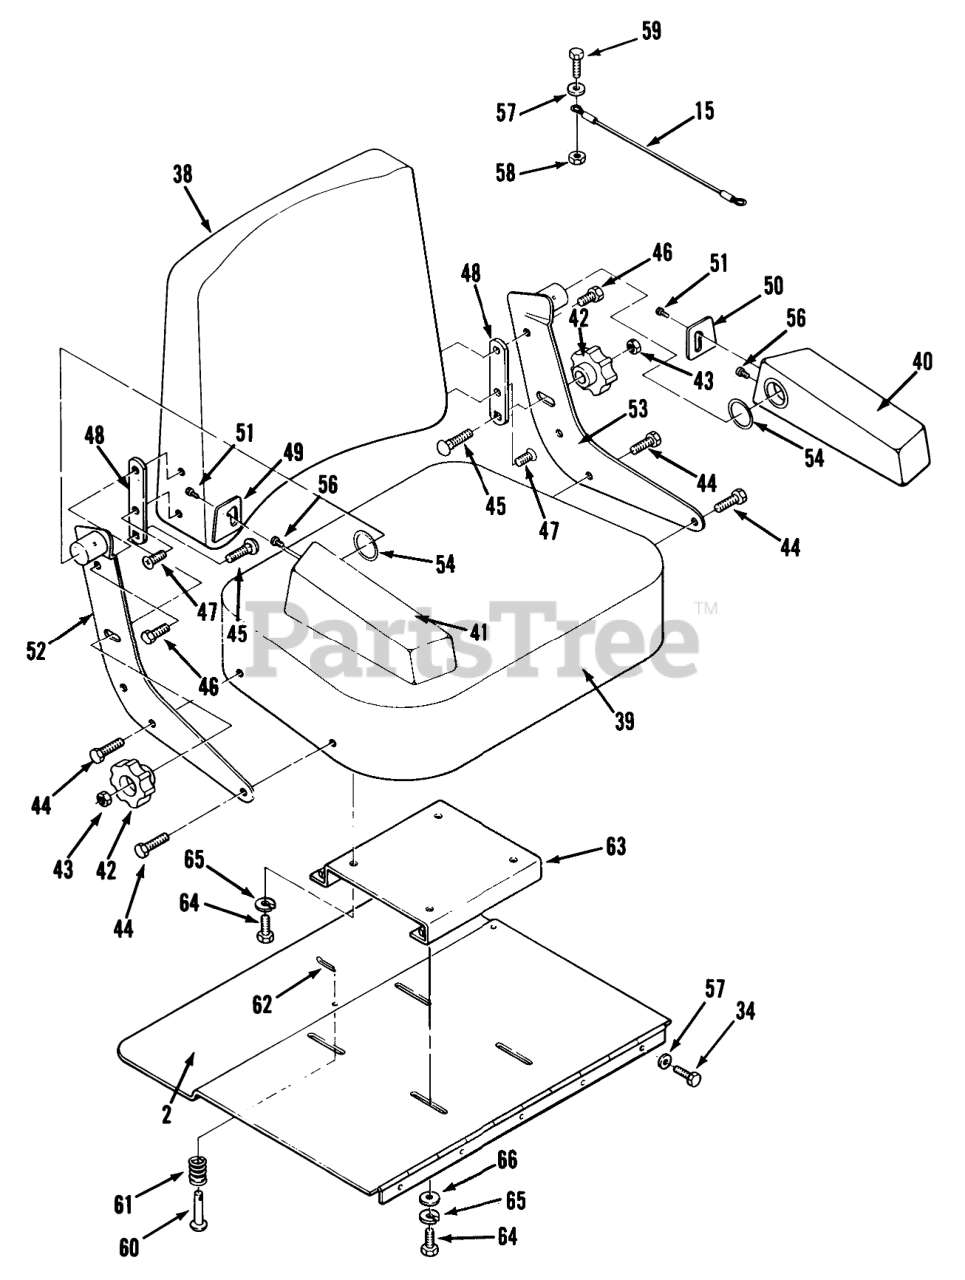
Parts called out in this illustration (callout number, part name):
2	Seat Mounting Bracket
15	Cable
34	Bolt
38	Seat Back
39	Seat Bottom
40	ARM REST LH
41	ARM REST RH
42	Knob-Lumbar Control
43	LOCK NUT
44	Bolt
45	Bolt
47	Screw-Phillips Hd
48	Lumbar Friction Plate
49	ARM REST PLATE RH
50	ARM REST PLATE LH
51	SCREW PAN HD 10-16X5
52	Back Support LH
53	BACK SUPT LH
54	WASHER
56	SHCS 1/4-20 X 1/2
57	WASHER
58	Nut
59	Bolt
61	SPRING-COMPRESSION
62	Cotter Pin
63	ASS'Y-SUPPORT SEA B
64	Bolt
65	LOCKWASHER
66	Washer
